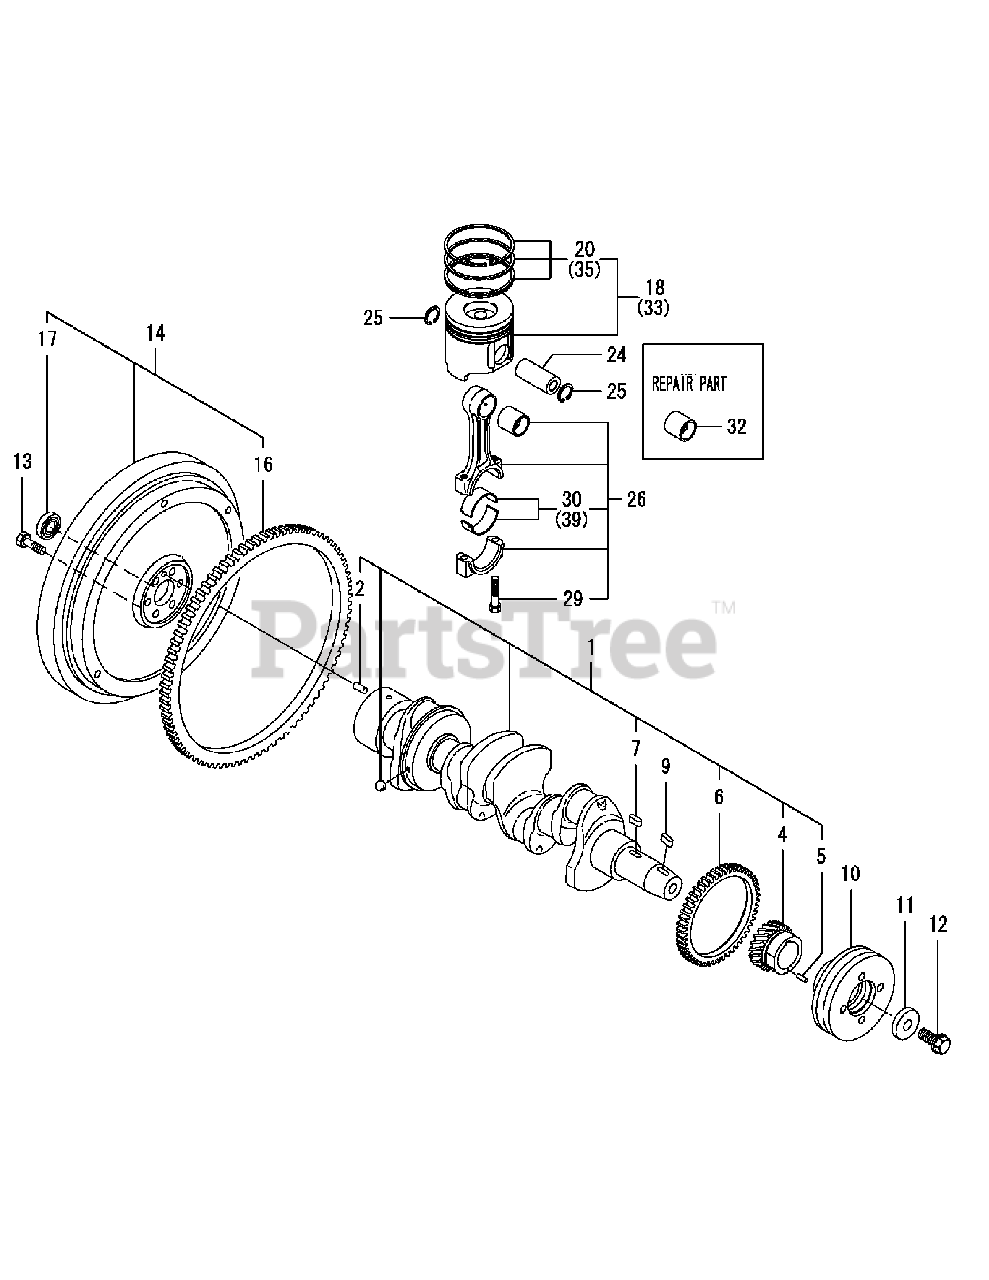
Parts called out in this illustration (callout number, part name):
1	CRANKSHAFT ASSY
2	PARALLEL PIN, M8X16
4	GEAR, CRANKSHAFT
6	GEAR, BALANCER
10	V-PULLEY, CRANKSHAFT
12	BOLT, V-PULLEY
13	BOLT, FLYWHEEL
20	RING SET, PISTON
26	ROD ASSY, CONNECTING
29	BOLT, CONNECTING ROD
30	METAL, CRANKPIN
32	METAL, PISTON PIN
33	PISTON W/RING .25OS
35	RING SET, PISTON .25
39	METAL.PIN US=0.25
